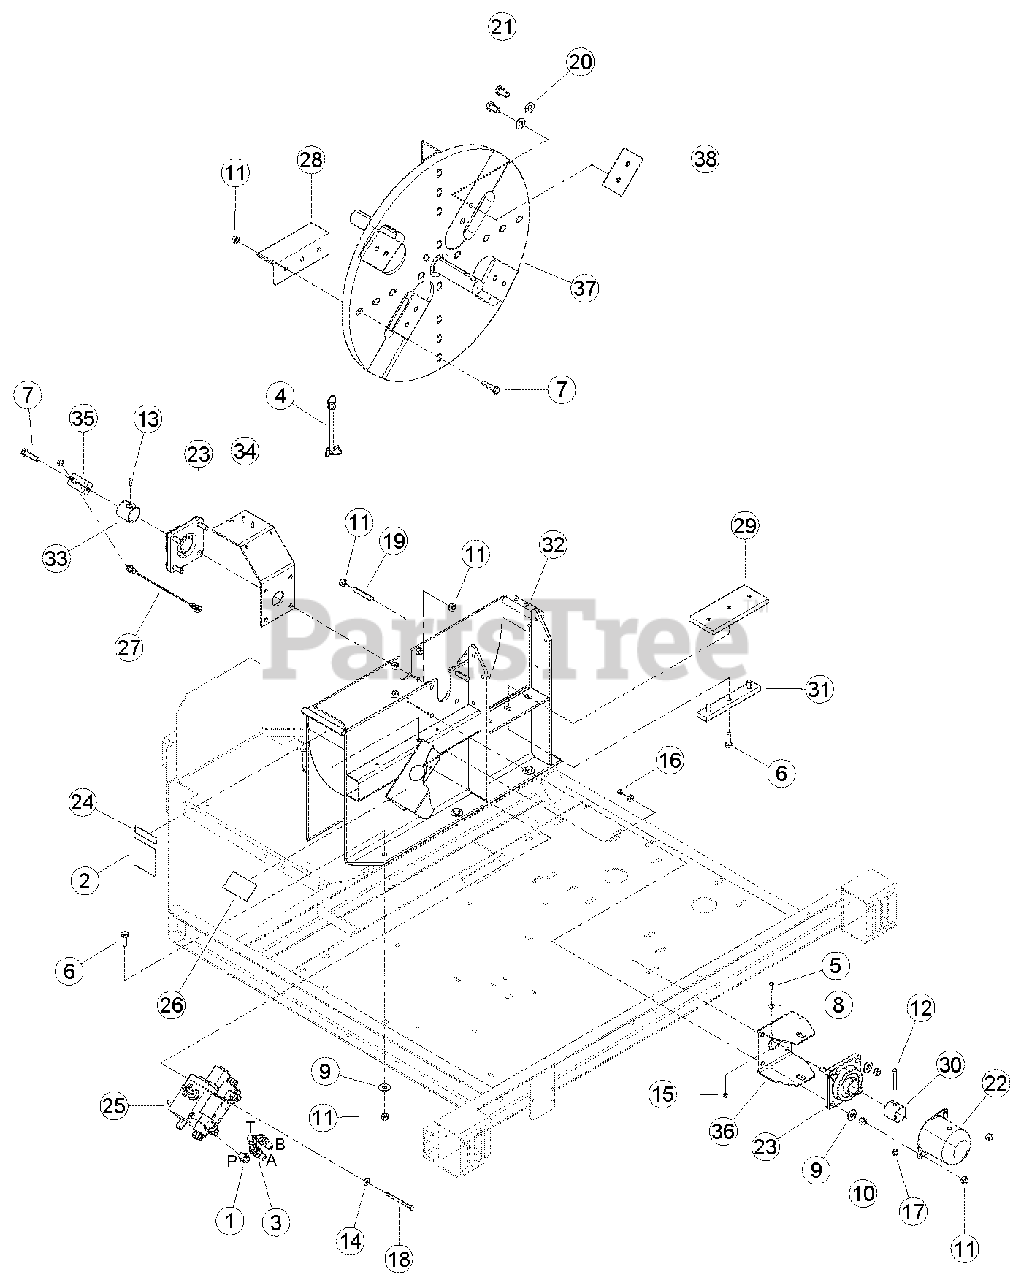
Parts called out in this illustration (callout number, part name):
1	ADAPTER, -8 MORING / -8 MJIC
2	DECAL, 112 DB (CE COMPLIANT MODELS)
3	ADAPTER, -8 MORB / -8 MJIC 45 DEG.
4	PIN, HITCH 1/2 X 6-1/2 W/LYNCH
5	BOLT, 1/4 X 3/4 HEX HD GR5 ZP
6	BOLT, 1/2 X 1-1/2 HEX HD GR5 ZP
7	BOLT, 1/2 X 2 HEX HD GR5 ZP
8	WASHER, 1/4 FLAT ZP
9	WASHER, 1/2 FLAT ZP
10	NUT, 1/2 HEX NC ZP
11	NUT, 1/2 CENTERLOCK GRB ZP
12	BOLT, 3/8 X 2-1/2 HHCS GR5 ZP
13	SCREW, 5/16-18 X 5/8 SQ HD SET
14	WASHER, 5/16 FLAT ZP
15	NUT, 1/4 NE NYLOCK ZP
16	NUT, 5/16 NE NYLOCK ZP
17	NUT, 3/8 NE NYLOCK ZP
18	BOLT, 5/16 X 4 HHCS GR5 ZP
19	STUD, 1/2-13 X 3 LG B7 ZP
20	WASHER, 5/8 SAE HARDENED
21	BOLT, M16 X 2 X 30 HEX HD W/PATCH
22	CAP, LARGE SHAFT
23	BEARING, 1-3/4 4 BOLT FLANGE
24	DECAL, 74950S INFO (CE COMPLIANT MODELS)
25	ASSEMBLY, CHIPPER VALVE
26	DECAL, FEED SPEED
27	SENSOR, M12 PNP PROXIMITY
28	PADDLE, BIG CHIPPER
29	PLATE, CHIPPER BOTTOM
30	COLLAR, CHIPPER LOCK
31	SPACER, CHIPPER ANVIL
32	WELDMENT, CHIPPER BOTTOM
33	WELDMENT, SPACER
34	WELDMENT, GUARD SUPPORT
35	BRACKET, SENSOR SHORT MOUNT
36	BRACKET, DISK LOCK
37	ASSEMBLY, 9 IN. CHIPPER DISK
38	KIT, CHIPPER BLADE
